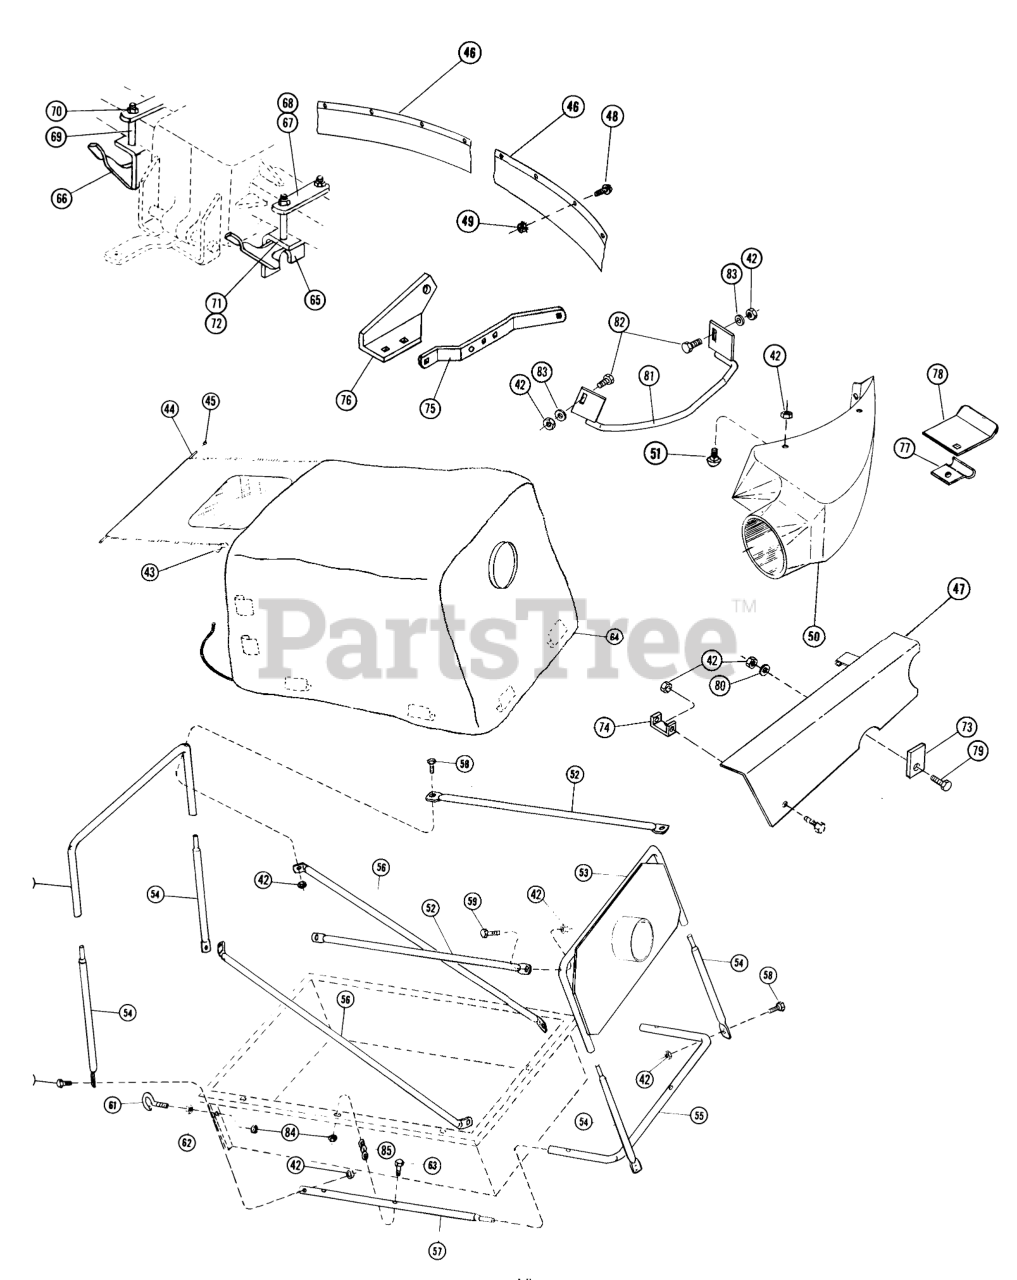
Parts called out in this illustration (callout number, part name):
42	Nut
43	5/16 DIA HOOK
44	Canopy Rod
45	Rubber Cap
46	ASSY COVER
47	Belt Guard Assembly
48	Screw
49	#10-24 Kep-Nut
50	NOZZLE ASSY
51	Bolt Carnage
52	Top Tube
53	Front Hose Adapter
54	Upright Brace
55	U-Tube
56	Cross Tube
57	Side Tube
58	Bolt
59	Bolt
60	U-Tube
61	EYE BOLT
62	Nut
63	Bolt
64	Cart Cover
65	Hitch Axle Mounting
66	Latch Hitch
67	Link
68	SPACER-BRACKET
69	Bolt-Carriage
70	NUT
71	BOLT
72	Washer
73	Belt Guard Plate
74	Belt Guard Bracket
75	Draft Bar-Mower
76	Deck Bracket-Mower
77	BRACKET
78	Footrest Plate
79	H H C S
80	Lockwasher
81	Blade Guard Assembly
82	Bolt
83	WASHER 5/16 SAE
84	Nut
